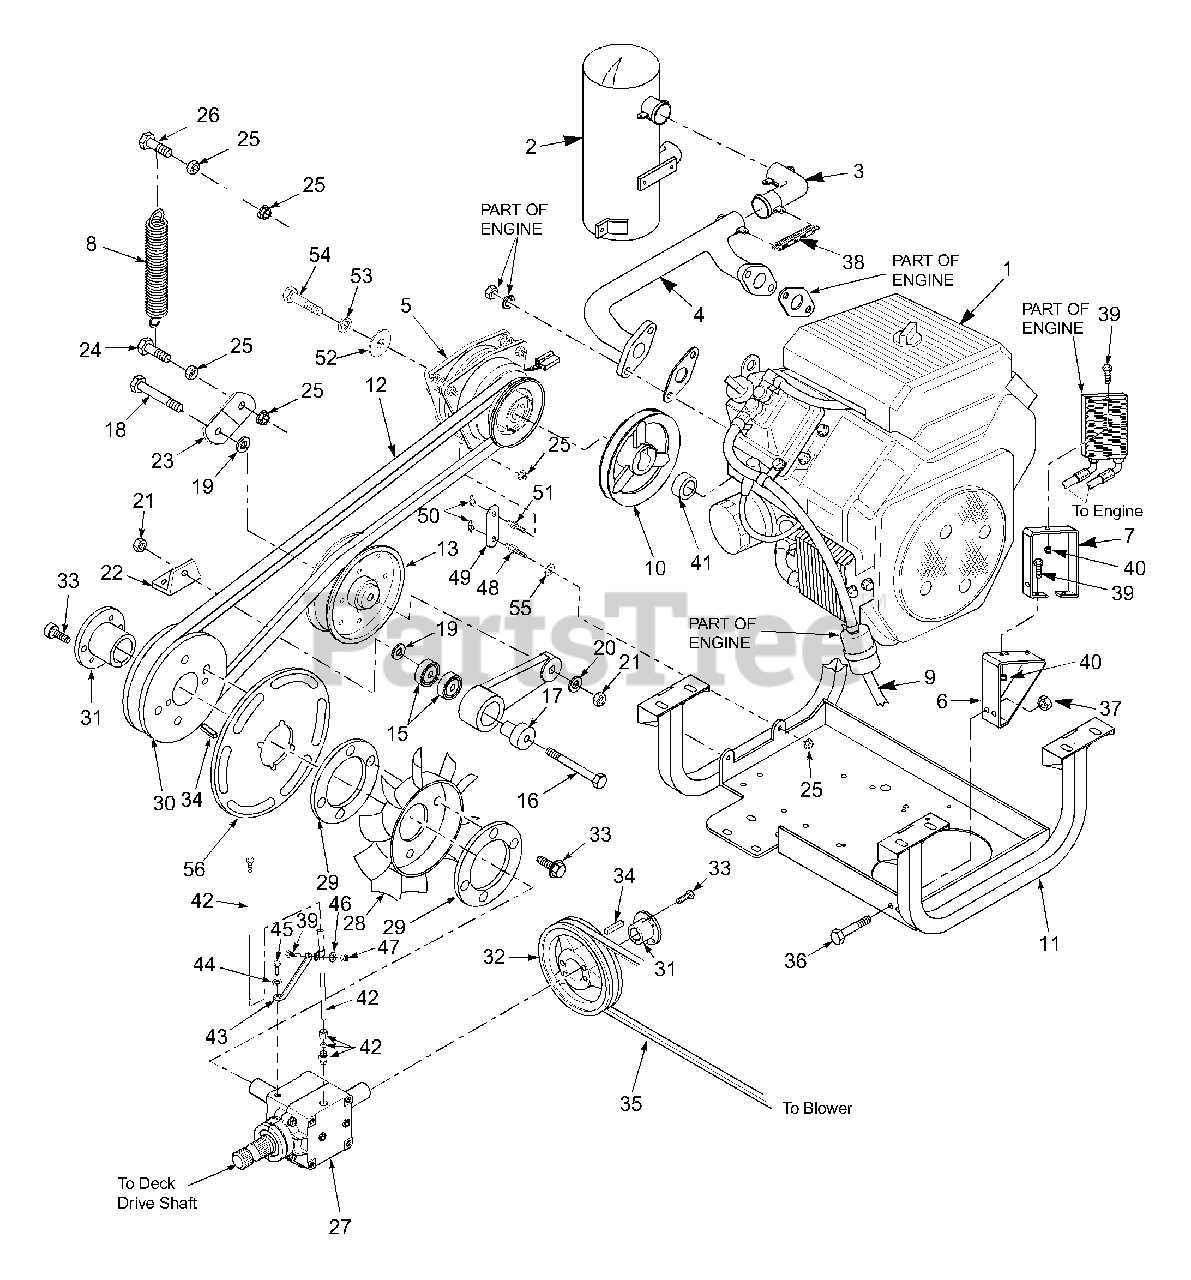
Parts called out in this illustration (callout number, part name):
1	Engine, 25 HP Kohler
2	Muffler
3	Pipe, Exhaust
4	Manifold, Exhaust
5	Clutch, PTO
6	Bracket, Oil Cooler
7	Guard, OIl Cooler
8	Spring, Gearbox Idler
9	Hose, Fuel 1/4" ID (order by the inch)
10	Pulley, 5.45" OD - 1.125 Bore
11	Weldment, Engine Deck
12	Belt, Gearbox Drive
13	Pulley, Idler 5.00" OD
15	Bearing, Idler Arm
16	Bolt, Hex Head 3/8-16 x 2.5"
17	Pivot, Idler
18	Bolt, Hex Head 3/8-16 x 2.75"
19	Flatwasher, 3/8"
20	Lockwasher, 3/8"
21	Nut, Elastic Stop 3/8"
22	Bracket, Mounting
23	Bracket, Spring Mounting
24	Bolt, Hex Head 3/8-16 x 1.5" Grade 8
25	Nut, Serrated Flange 3/8"
26	Bolt, Hex Head 3/8-16 x 1.75" Grade 8
27	Gearbox, T-Drive
28	Fan, Cooling
29	Spacer, Fan
30	Pulley, 4.95" OD
31	Hub, Tapered 1" Bore
32	Pulley, 5.35" OD
33	Capscrew, Hex Head 1/4-20 x 1"
34	Key, 1/4 x 1/4 x 1.25"
35	Belt, Blower
36	Bolt, Hex Head 3/8-16 x 1.5"
37	Nut, Elastic Stop 3/8-16
38	Spring, Exhaust
39	Bolt, Hex Head 1/4-20 x .75"
40	Nut, Serrated Flange 1/4-20
41	Spacer, Crankshaft
42	Dipstick Assembly
43	Bracket, Dipstick Tube
44	Lock Washer, 5/16"
45	Bolt, Hex Head 5/16-18 x 3/4"
46	Flatwasher, 1/4-.312 x .750 x .065
47	Nut, Elastic Stop 1/4-20
48	Stud, Anti-Rotation
49	Link, Anti-Rotation
50	Pin, Rue Cotter 3/8 Dia.
51	Stud, Anti-Rotation
52	Washer, 7/16-.469 x 1.75 x .25
53	Lockwasher, 7/16"
54	Bolt, Hex Head 7/16-20 x 3"
55	Flatwasher, 3/8-.391 x .938 x .105
56	Disk, Fan Support
